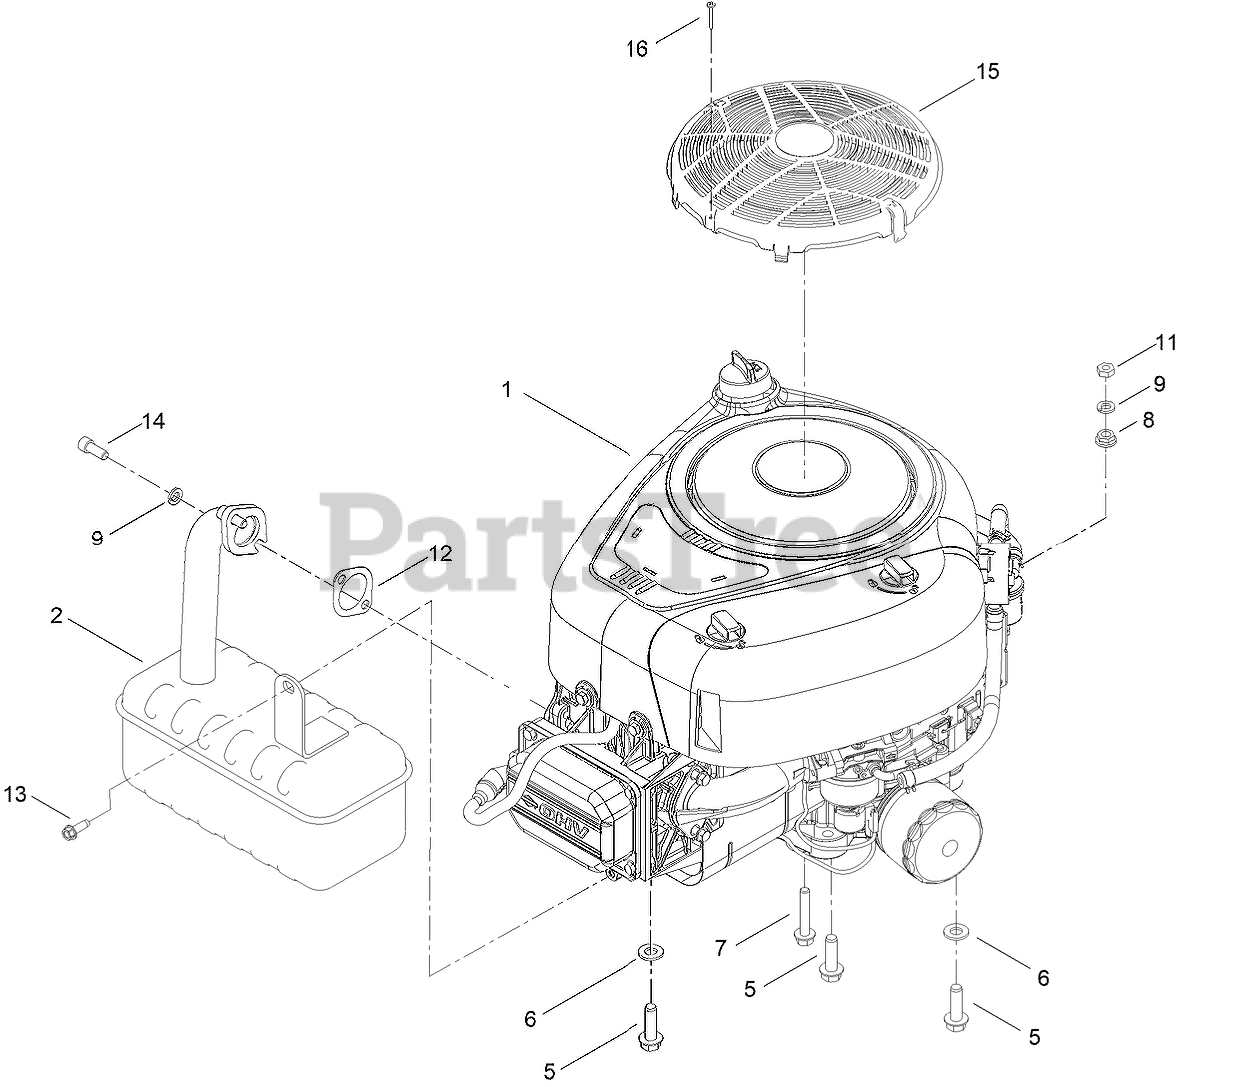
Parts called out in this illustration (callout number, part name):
1	ENGINE-BRIGGS STRATTON PROFESSIONAL
2	MUFFLER
5	SCREW-THD
6	WASHER-FLAT
7	SCREW-HWH
8	NUT-HF
9	WASHER-LOCK
11	NUT-JAM
12	GASKET-EXHAUST, BRIGGS
13	SCREW-HWHTF
14	SCREW-HSH
15	COVER-FAN
16	SCREW-FAN
